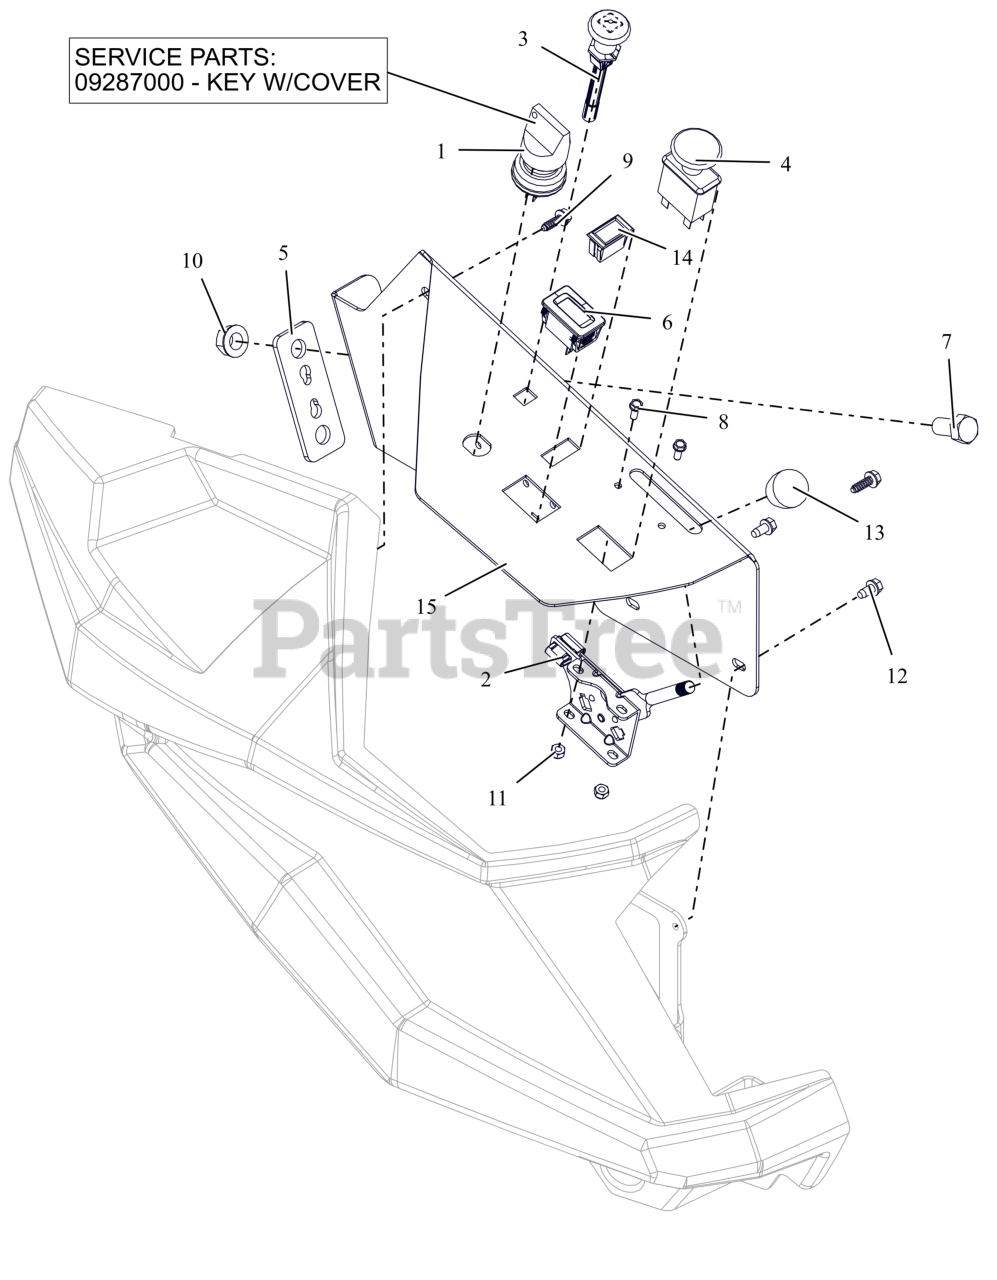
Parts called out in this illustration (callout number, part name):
1	SWITCH, IGNITION
1	KEY, W/ SHIELD
2	CABLE, PRO THROTTLE CONTROL
3	CABLE - CHOKE, SNAP-IN
4	SWITCH, CLUTCH
5	PLATE, CONTROL PANEL SPACER
6	HOUR METER
7	BLT, HEX .50-13X1.00 G5 ZCC
8	BLT, HWH #10-24X.50 ZCC
9	SCR, PLASTITE-HWH 0.25 X 0.75 ZC120
10	NUT-LK-TOP-FLG .500-13 GF ZCC
11	NUT-LK-NYL #10-24 G2 ZCC
12	SCR-TAP .25-20X.50 HWH ZCC
13	KNOB-CONTROL-BLACK .38-16X.50
14	SWITCH,BLANK
15	PANEL, HD CONTROL (RED)
